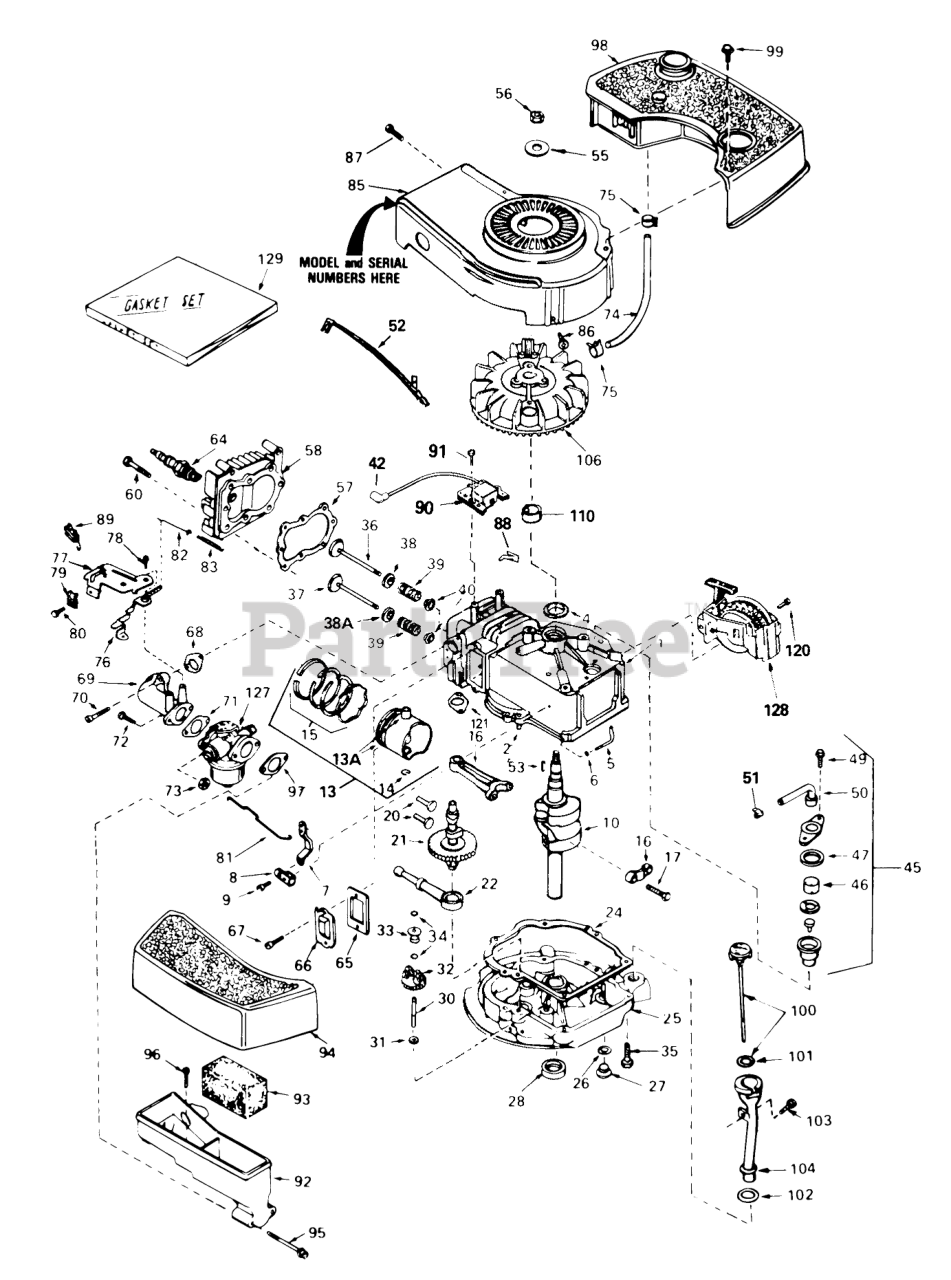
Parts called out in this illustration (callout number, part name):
1	Cylinder Assembly (Incl. Ref. #2 & 4)
2	Pin-Dowel
4	Seal-Oil
5	Rod-Governor (Incl. Ref. #6)
6	Washer-Flat
7	Governor Lever
8	Clamp-Lever, Governor
9	Screw
10	Crankshaft
13	Piston-Pin & Ring Assy. (Std.)(Incl. Ref. #13A, 14 & 15)
13	Piston-Pin & Ring Assembly (.010 oversize)(Incl. Ref. #13A, 14 & 15)
13	Piston-Pin & Ring Assembly (.020 oversize)(Incl. Ref. #13A, 14 & 15)
13A	Piston & Pin Assembly (Std.)(Incl. Ref. #14)
13A	Piston & Pin Assembly (.010 oversize)(Incl. Ref. #14)
13A	Piston & Pin Assembly (.020 oversize)(Incl. Ref. #14)
14	Ring-Retaining, Piston Pin
15	Ring Set (Std.)
15	Ring Set (.020" OS)
15	Ring Set (.010" OS)
16	Rod Assembly-Connecting (Incl. Ref. #17)
17	Bolt-Rod, Connecting
20	Lifter-Valve
21	Camshaft(Mech.Comp. Release)
22	Oil Pump ASM
24	Gasket
25	Flange Assembly-Mounting (Incl. Ref. #26, 27, 28 & 30)
26	Gasket-Oil Drain
27	Plug Oil Drain
28	Seal Oil
30	Shaft-Governor
31	Washer-Flat
32	Gear Assembly-Governor (Incl. Ref. #31)
33	Spool-Governor
34	Ring-Retaining
35	Screw (1/4-20 x 1-1/4)
36	Valve-Intake (Std.)(Incl. Ref. #40)
36	Valve-Intake (1/32" oversize)(Incl. Ref. #40)
37	Valve-Exhaust (Std.)(Incl. Ref. #40)
37	Valve-Exhaust (1 /32" oversize)(Incl. Ref. No. 40)
38	Seal Assy., Intake
38A	Cap-Upper Valve Spring
39	Spring-Valve
40	Cap-Valve, Spring
42	Cover-Spark Plug
45	Breather Assembly (Incl. Ref. #46 thru 51)
46	Element-Breather
47	Gasket-Breather
49	Screw (10-24 x 9/16)
50	Tube, Breaker
51	Clip, Breather
52	Wire-Ground
53	Key-Flywheel
55	Washer-Belleville
56	Nut-Flywheel
57	63573 GIL 42 SNWTHW
58	Head-Cylinder
60	Screw (5/16-18x1-1/2)
64	Spark Plug-Resistor (R J19 L M)
65	Gasket-Breather
66	Cover-Valve
68	Gasket-Intake
69	Pipe-Intake (Incl. Ref. #68)
70	Screw (1/4-20 x 1)
71	Gasket-Carburetor
72	Screw (1/4-28 x 7/8)
73	Nut and Lock Washer (1/4-28)
74	Line-Fuel
75	Clamp-Line, Fuel
76	Lever Control
77	Control Assembly-Speed (Incl. Ref. #76, 78 & 89)
78	Screw, Hex Washer Hd Shoulder Self-Tap
79	Conduit
80	Screw (10-32 x 3/8)
81	Link-Throttle
82	Link Governor Spring
83	Spring Governor
85	Housing-Blower
86	Screw (1/4-20x19/32)
87	Screw (10-24 x 9/16)
88	Clip-Wire
89	Terminal
90	Solid State
91	Screw
92	Body Air Cleaner
93	Filer, Air
94	Cove, Air Cleaner
95	Screw Fil Hd.
96	Screw, Hex Washer Hd Shoulder Self-Tap
97	Gasket-Air Cleaner
98	Tank-Fuel
99	Screw (10-32 x 35/64)
100	Dipstick-Oil (Incl. Ref. #101)
103	Screw (10-32 x 1/2)
104	Tube-Oil Fill
106	Flywheel
120	Screw (1/2-20x5/8)
121	Gasket Exhaust
127	Carburetor (Incl. Ref. #71)
128	Starter-Sidemount
129	Gasket Set (Incl. items marked)
